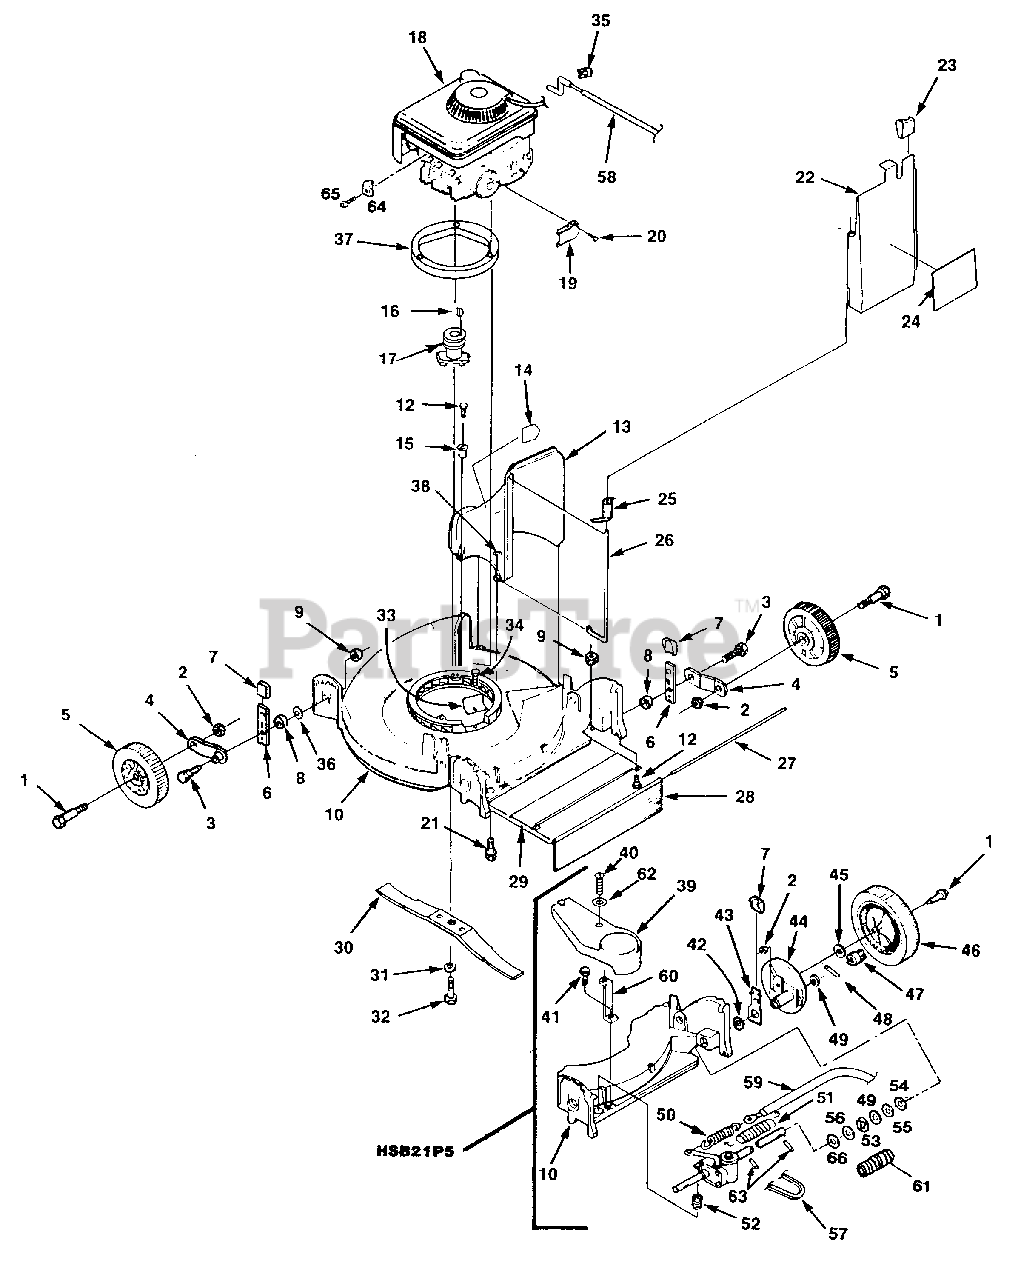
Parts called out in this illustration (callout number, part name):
1	Axle Assembly
2	Nut-Jam 3/8-16
3	Bolt - Height adjusting
4	Arm-Wheel htg. adj.
5	Wheel & Tire
6	Spring - Index (Front)
7	KNOB- Indexing spring
8	SPACER- Wheel height adj.
9	NUT - Flange 5/16-18
12	SCREW 1/4-20 x 3/4"
13	CHUTE - Discharge
14	DECAL - CPSC
15	EYELET - Stimpson
16	KEY - Woodruff
17	ADAPTER - Blade
18	ENGINE
19	DEFLECTOR
20	SCREW - #8-32 x 3/8"
21	SCREW - 3/8-16 x 2 1/4"
22	DOOR - Chute
23	KNOB - Index spring
24	DECAL - Door (warning)
25	SPRING - Chute door
26	PIN - Hinge
27	ROD - Drag flap
28	FLAP - Drag
29	COVER - Rear
30	BAR - Cutter
31	WASHER - Lock 3/8"
32	SCREW - Hex hd. 3/8-24 x 1 1/4"
33	COVER - Belt Opening
34	SCREW - 1/4-20 x 1/2"
35	STOP - Rope
36	WASHER - Flat (5/16")
37	RING - Engine
38	WASHER - Plain (1/4")
39	COVER - Drive
40	SCREW - 1/4-20 x 3/4"
41	SCREW - Hex #10-16
42	SPACER - Rear hgt. adj.
43	SPRING - Index
44	SUPPORT - Drive wheel
45	WASHER
46	WHEEL & TIRE
47	PINION (L.H.)
48	PIN - Drive
49	WASHER
50	SPRING - Extension
51	COVER - Spring
52	SPRING - Compression
53	RING - Eaton
54	WASHER
55	WASHER
56	WASHER
57	BELT - Drive
58	CONTROL - Engine
59	CABLE - Traction control
60	SUPPORT - Belt cover
61	COVER - Drive Shaft
62	WASHER - Plain
63	PIN - Roll 1/8 x 7/8
64	CLAMP - CABLE
65	SCREW - #10-16 x 5/8
66	WASHER - Thrust
